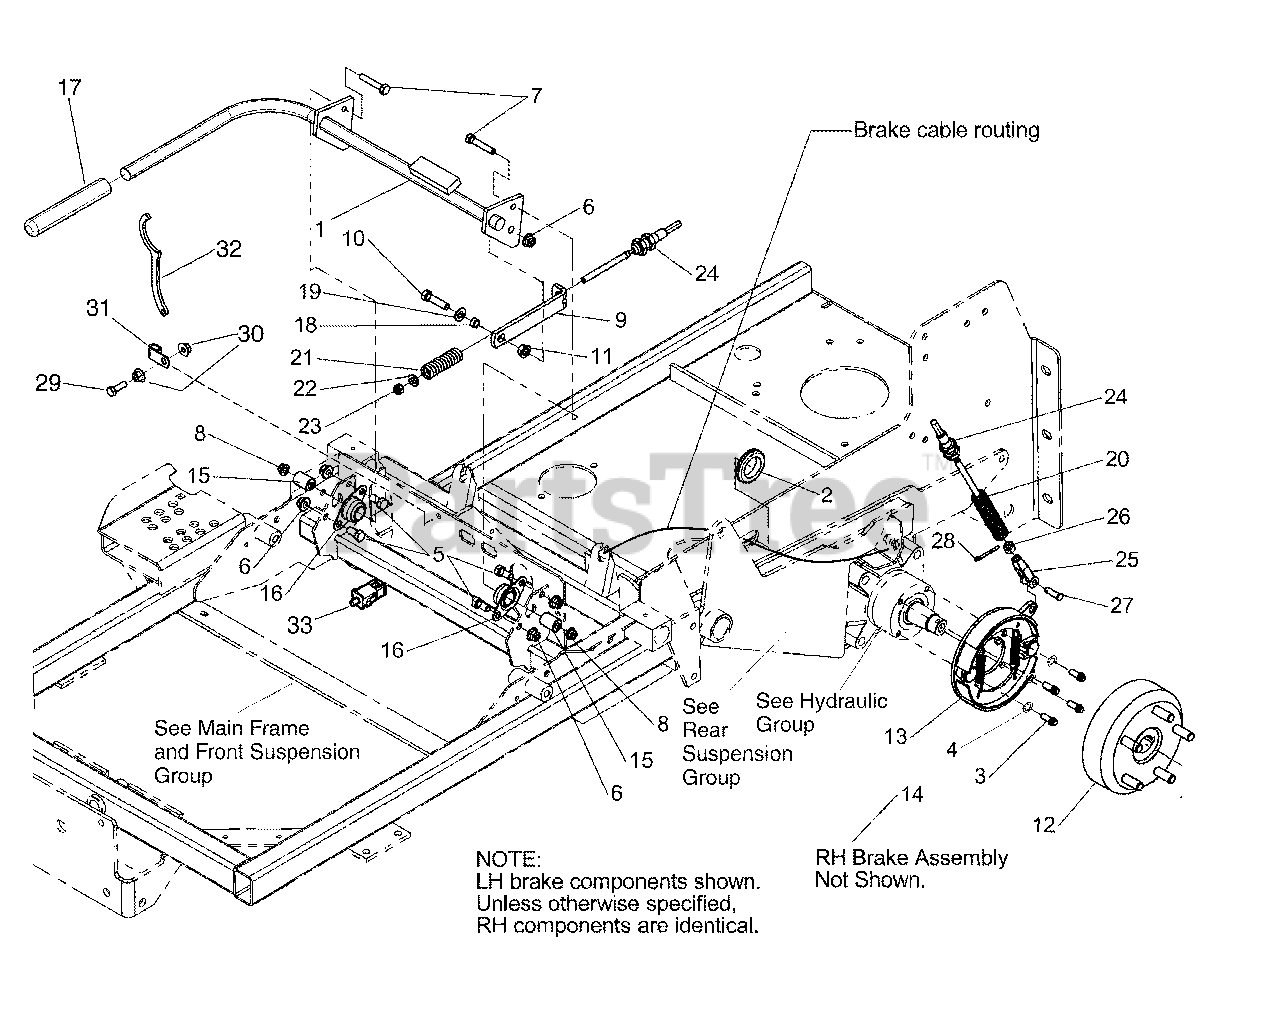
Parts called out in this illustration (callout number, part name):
1	WELD, BRAKE SHAFT - BLK
2	GROMMET, 1-1/4"
3	BOLT, 5/16-18 X 3/4" 12 Point Flange
4	WASHER, 5/16 LOCK
5	BOLT, 3/8-16 X 3/4"
6	NUT, 3/8-16 Hex Nylock Flange
7	BOLT, 5/16-18 X 1-3/4"
8	NUT, 5/16-18 Hex Nylock Flange
9	LINK, BRAKE LOCK - BLK
10	BOLT, 3/8-16 X 1-1/2"
11	NUT, 3/8-16 Hex Serrated Flange
15	SPACER, .32 X .75 X 1.06
16	BEARING, FLANGE
18	SPACER, .38 X .50 X .27
19	WASHER, 3/8" SAE
20	SPRING, Compression
21	SPRING, Compression
22	WASHER, 5/16" SAE
23	NUT, 5/16-24 Hex Nylon Lock
24	PARKING BRAKE CABLE
25	CLEVIS, 5/16-24, Plastic
26	NUT, 5/16-24 Hex
27	CLEVIS PIN, 5/16" X 1"
28	COTTER PIN, 1/8" X 1-1/4"
29	NUT, 5/16-18 HEX SERRATED FLANGE (LARGE)
30	CLAMP, 5/16, DOUBLE, WIRE & TUBE
31	SPANNER WRENCH
32	BOLT, 5/16-18 X 1 GD5 YZ
33	SWITCH, DP NO/NC SNAP-IN
